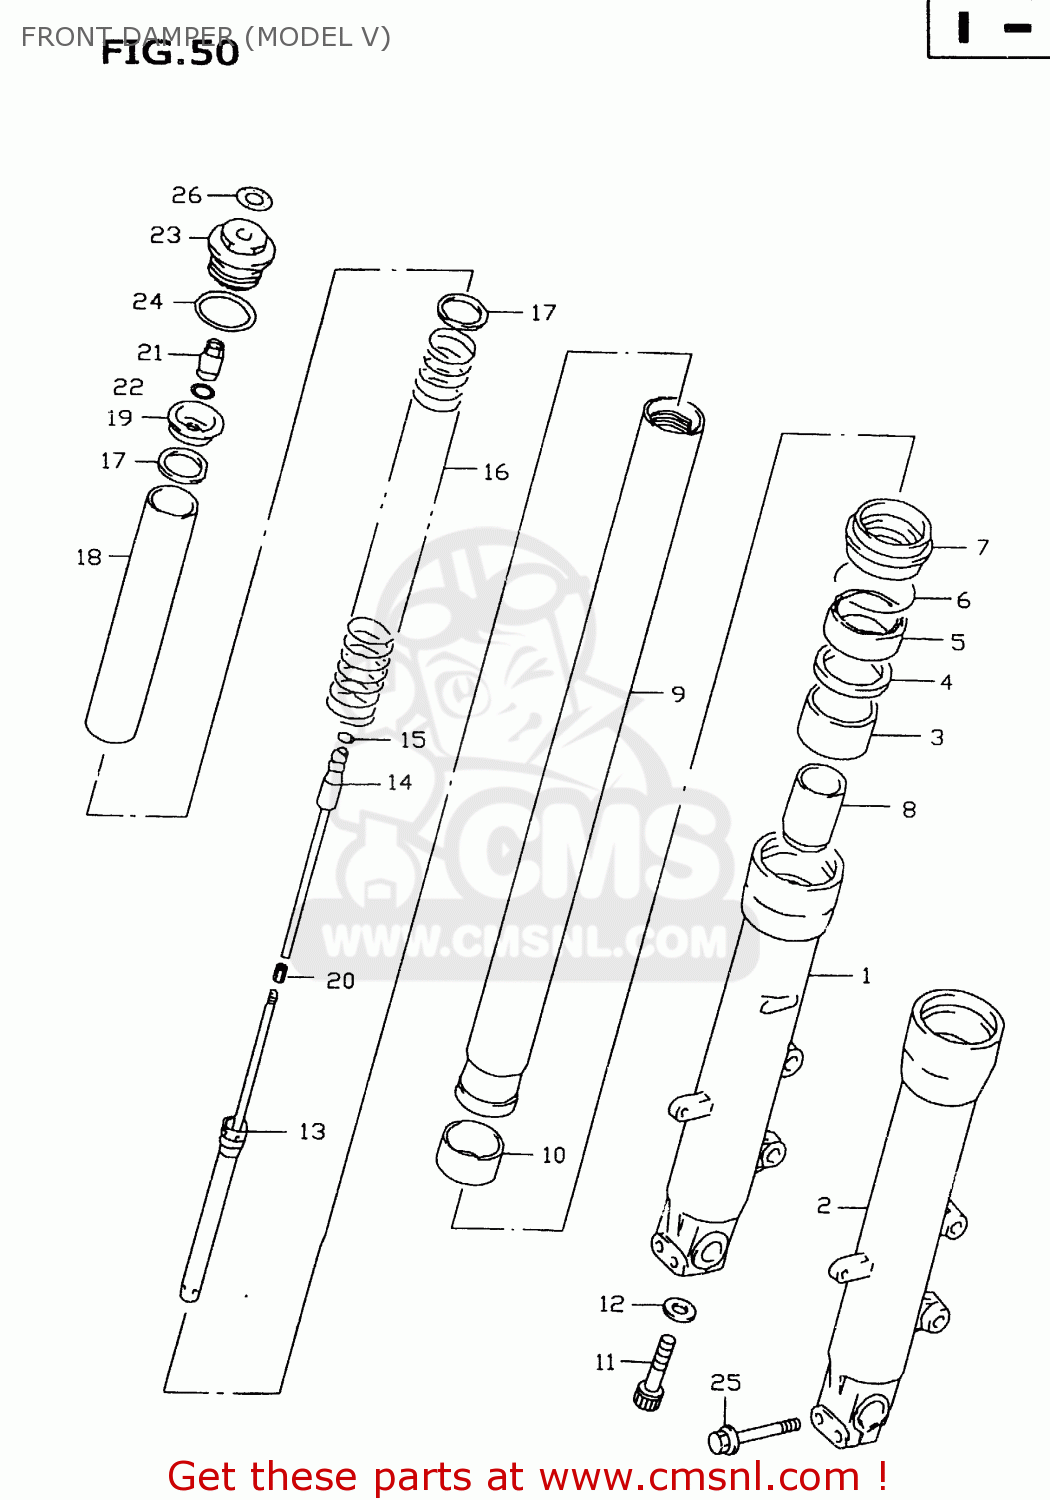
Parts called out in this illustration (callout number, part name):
1	TUBE,OUTER,R
2	TUBE,OUTER,LEFT
3	BUSH,GUIDE
4	SPACER,SEAL
5	SEAL,OIL
6	RING,OIL SEAL STOPPER
7	SEAL,DUST
8	PIECE,OIL LOCK
9	TUBE,INNER
10	BUSH,SLIDE
11	BOLT(8X27)
12	GASKET (NAS)
13	ROD,FR DAMPER
14	ROD,ADJUST
15	O RING(D:1.9,ID:3.8)
16	SPRING,FRONT
17	JOINT,SPRING
18	COLLAR,SPRING
19	SEAT,SPRING UPR
20	NUT
21	ADJUSTER,SPRING
22	O-RING (D:2.4 ID:13.8)
23	BOLT,FORK
24	O RING
25	BOLT
26	LABEL
